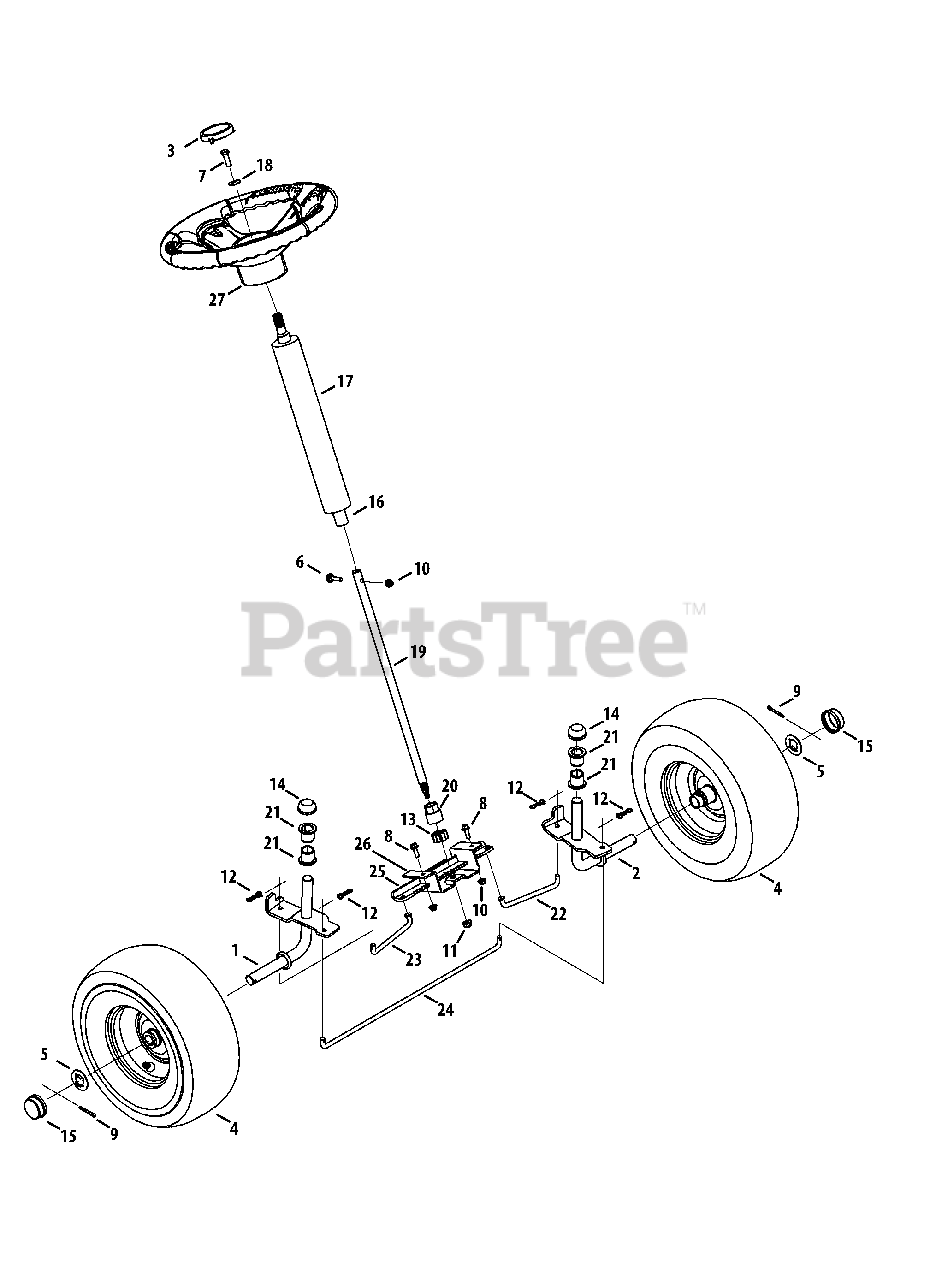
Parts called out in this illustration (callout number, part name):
1	Front Axle Assembly, RH
2	Front Axle Assembly, LH
3	Cap, Troy-Bilt
4	Complete Wheel Assembly
5	Washer, .781 x 1.59
6	Shoulder Screw, .375 x .148 x 1/4-20
7	Hex Head Screw, 5/16-18:1.00
8	Carriage Screw, 1/4-20, .62
9	Cotter Pin, 5/32 x 1.25
10	Flange Lock Nut, 1/4-20
11	Flange Lock Nut, 3/8-16
12	Bow-Tie Cotter Pin, 72
13	Steering Pinion Gear
14	Push Cap, 3/4
17	Steering Sleeve
18	Bevel Washer, .340X.872X.060
19	Steering Shaft, .625 OD X 18.03
20	Hex Flange Bearing, 5/8
21	Flange Bearing, .760 X .941 X 1.0
22	Steering Rod, LH
23	Steering Rod, RH
24	Front Tie Rod
25	Steering Rack Plate
26	Lower Steering Bearing
27	Steering Wheel, Soft Grip
